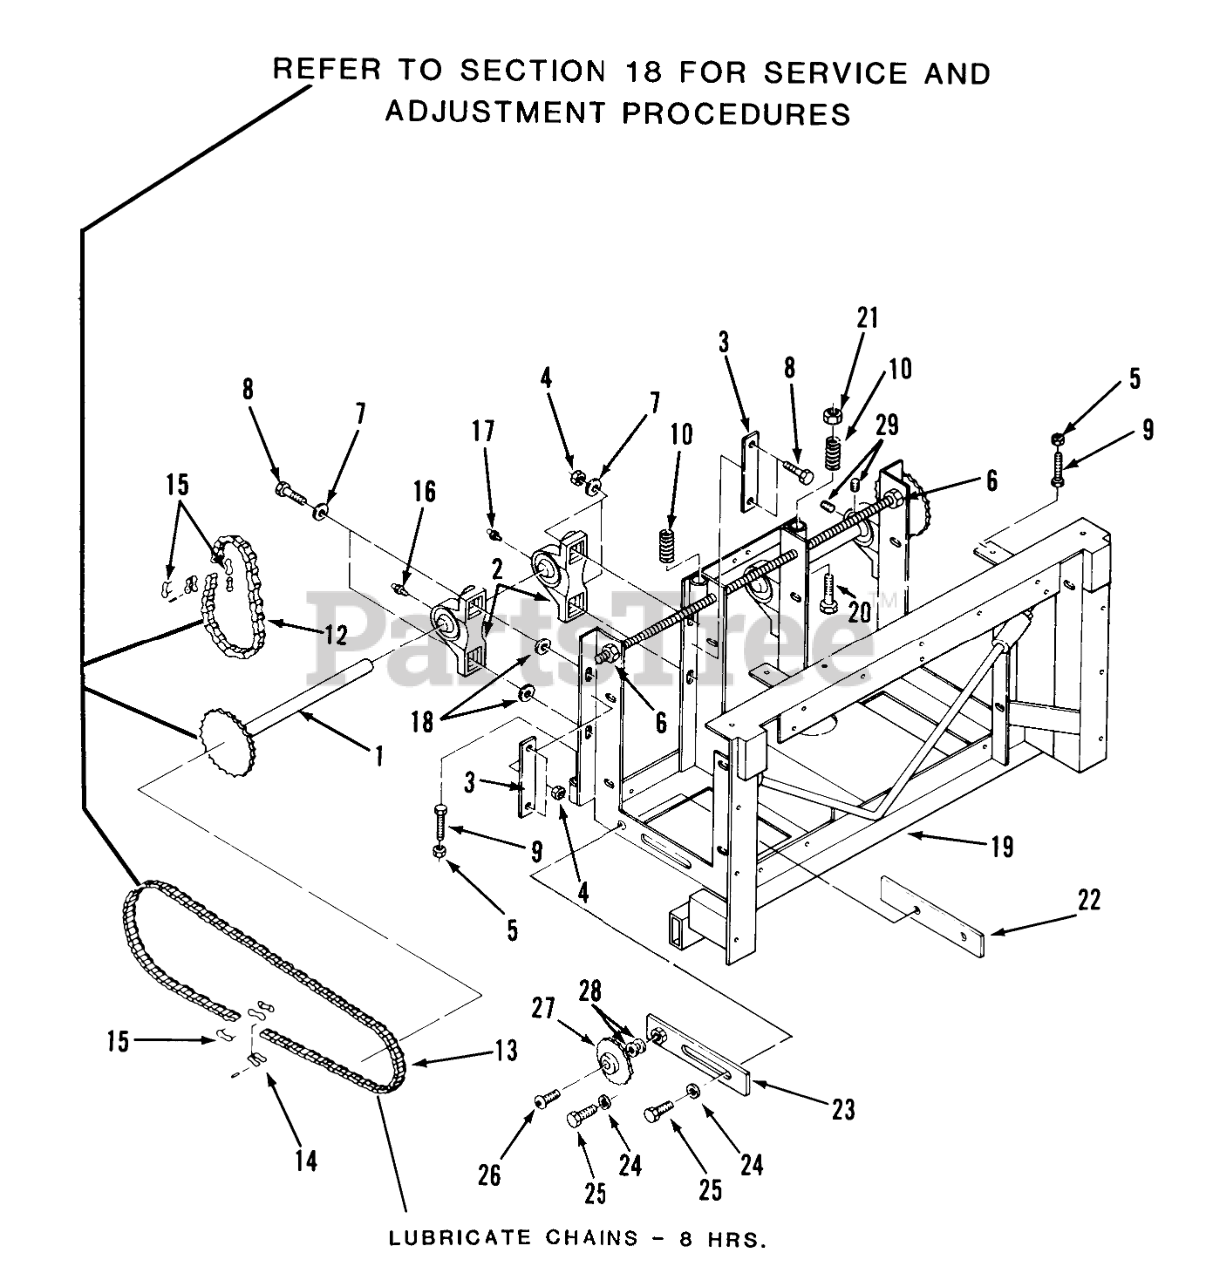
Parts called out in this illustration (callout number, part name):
1	Jackshaft
2	Pillow Block Bearing
3	PLATE PILLOW BLOCK
4	NUT
5	Nut
6	Eslok Nut
7	Washer
8	Bolt
9	Hex Bolt 5/16-18 x 1 1/2
10	SPR SEAT (LG)
12	Primary Chain (includes items 14 & 15)
13	Secondary Chain (includes items 14 & 15)
14	HALF LINK
15	Master Link #50
16	Fitting-Grease
17	Grease Fitting 45deg.
18	Washer
18	WASHER THIN FENDER
19	Transaxle Frame
20	Bolt 5/16-18 x 2
21	Flanged Nut
22	Back-up Plate
23	ASSY-CHAIN TENSIO B
24	Washer
25	BOLT
26	Idler Sprocket Bolt
27	IDLER SPROCKET 20288
28	WASHER
29	Set Screw 10-32 x 1/4
